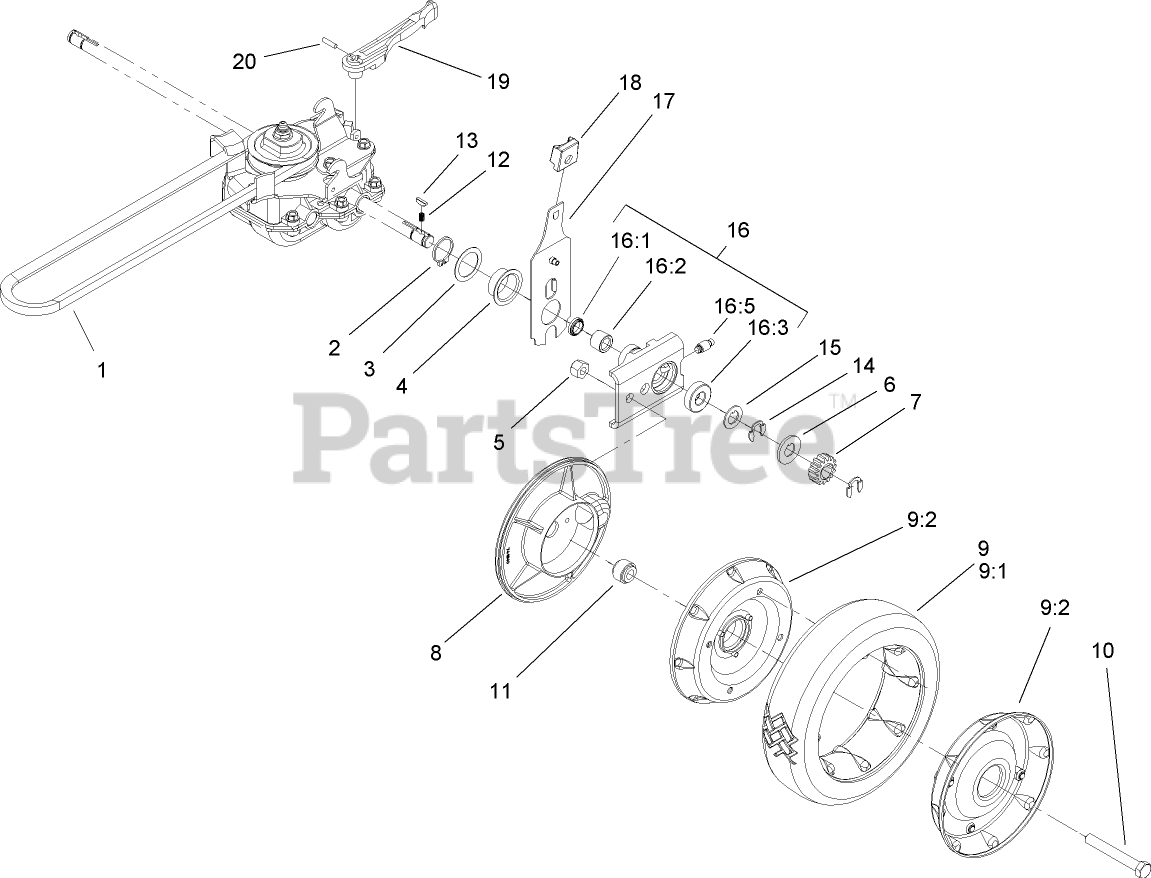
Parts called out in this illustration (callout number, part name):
1	V-BELT
2	RING-RETAINING
3	WASHER
4	CAP-END
5	NUT-LOCK, CONE
6	WASHER-THRUST, OUTER
7	GEAR-PINION
8	COVER-WHEEL
9:2	Wheel ASM
10	SCREW-HH
11	SPACER-COVER, WHEEL
12	SPRING-COMPRESSION
14	RING-RETAINING
15	WASHER-THRUST, OUTER
16	PIVOT ARM ASM
16:1	SEAL-OIL
16:3	BEARING-WHEEL
17	REAR SPRING ARM ASM
18	KNOB-ARM
19	LEVER-SHIFT
20	PIN-SPRING
